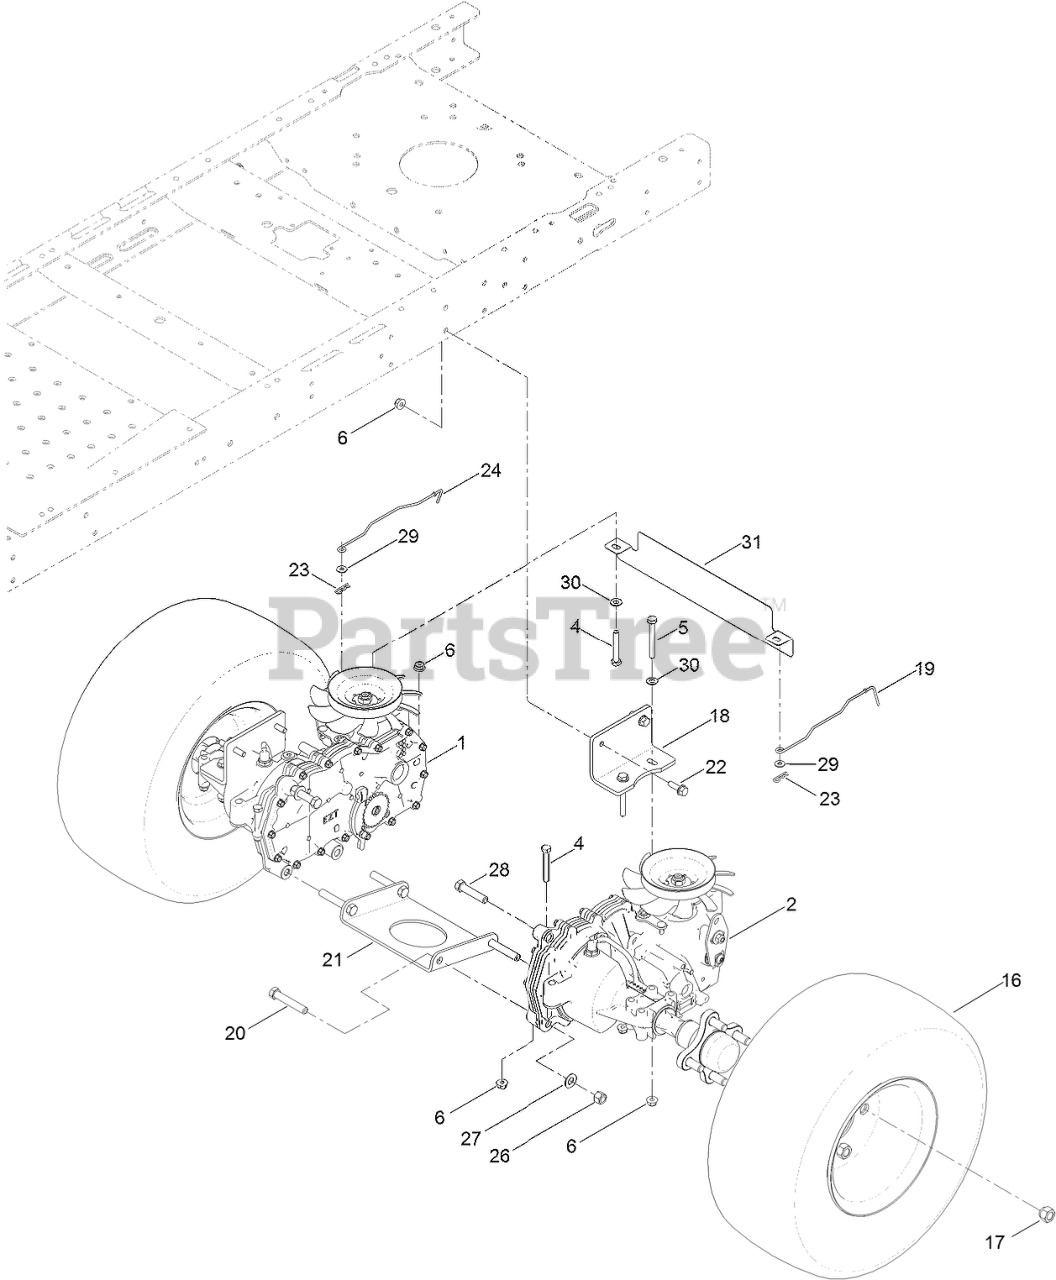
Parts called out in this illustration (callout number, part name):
1	RH HYDRO TRANSAXLE ASM
2	LH HYDRO TRANSAXLE ASM
4	SCREW-HH
5	SCREW-HH
6	NUT-HF, NI
16	2 PLY TIRE AND WHEEL ASM
17	NUT-LUG
18	MOUNT-HYDRO
19	ROD-BYPASS, LH
20	SCREW-HH
21	PLATE-CROSS, HYDRO
22	SCREW-HHF
23	PIN-COTTER
24	ROD-BYPASS, RH
26	NUT-LOCK, NI
27	WASHER-FLAT
28	SCREW-HH
29	WASHER
30	WASHER-PLAIN
31	GUARD REAR, WIDE
